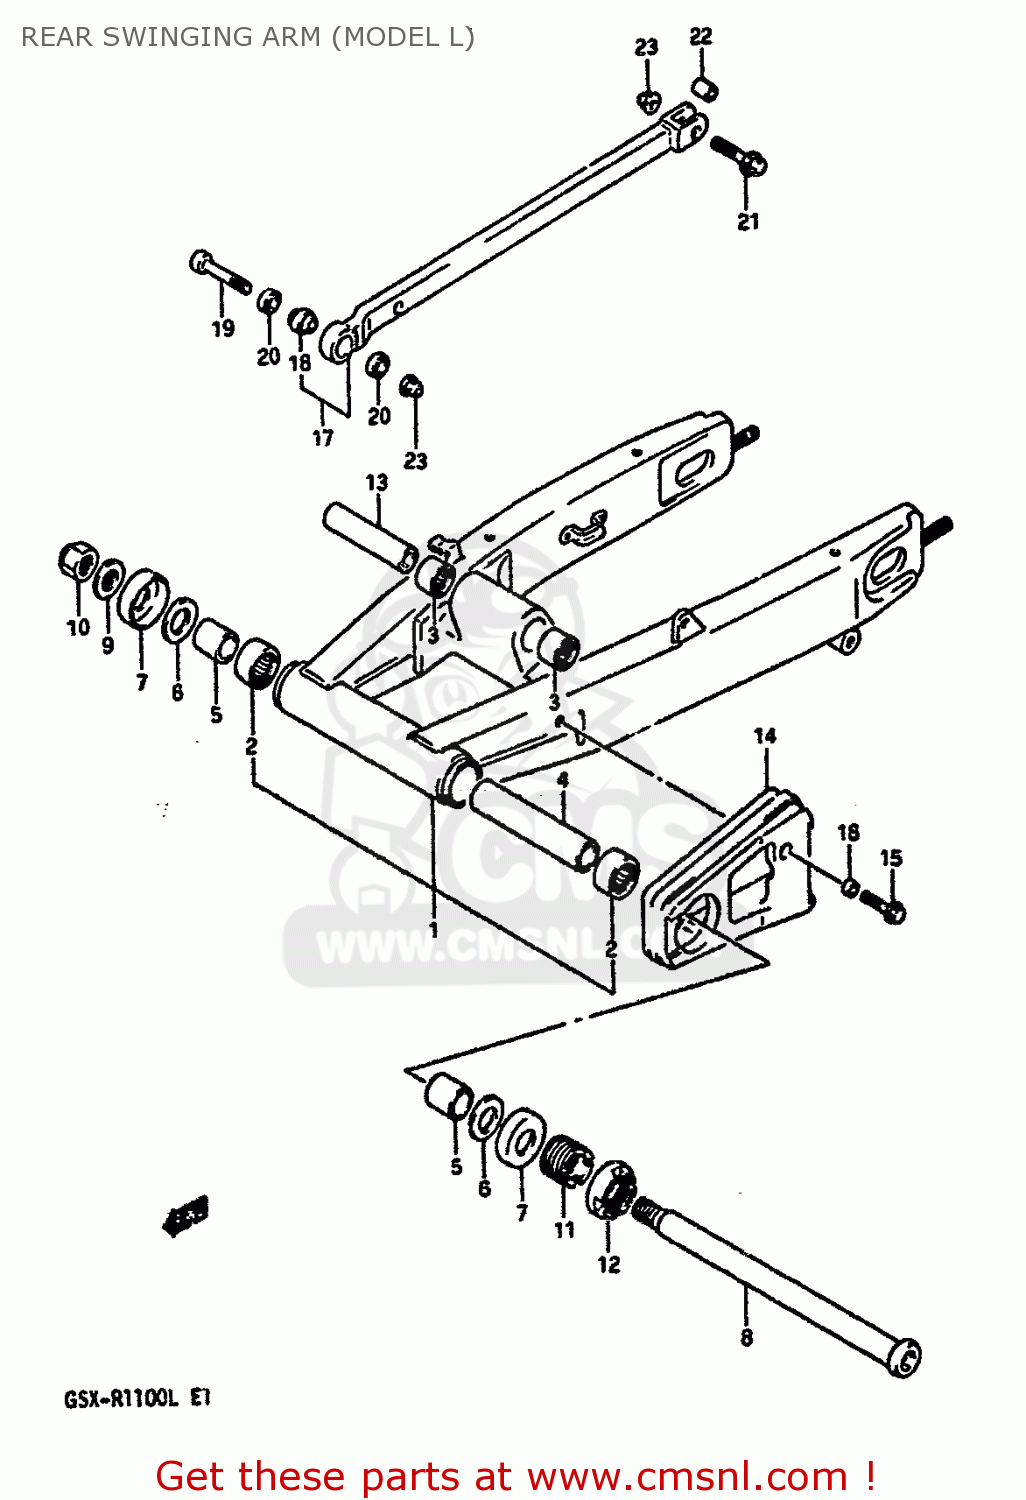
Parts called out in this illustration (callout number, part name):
1	SWING ARM ASSEMBLY,REAR
2	BEARING(25X33X30)
3	BEARING(20X27X23.5)
4	SPACER,RR SWGARM PIVOT CTR
5	SPACER,RR SWGARM PIVOT BERRING
6	WASHER
7	DUST SEAL,RR SWGARM PIVOT
8	SHAFT,REAR SWING ARM PIVOT
9	WASHER
10	NUT
11	BOLT,RR SWGARM PIVOT
12	NUT,REAR SWING ARM PIVOT
13	SPACER,RR CUSHION ROD
14	BUFFER,CHAIN TOUCH DEFENSE
15	BOLT 6X20,WITH PLAIN WASHER
16	SPACER
17	TORQUE LINK SET,REAR
18	SPHERICAL BEARING,TORQUE
19	BOLT(8X48)
20	21
21	BOLT(8X38)
22	SPACER,RR TORQUE LINK RR
23	NUT
